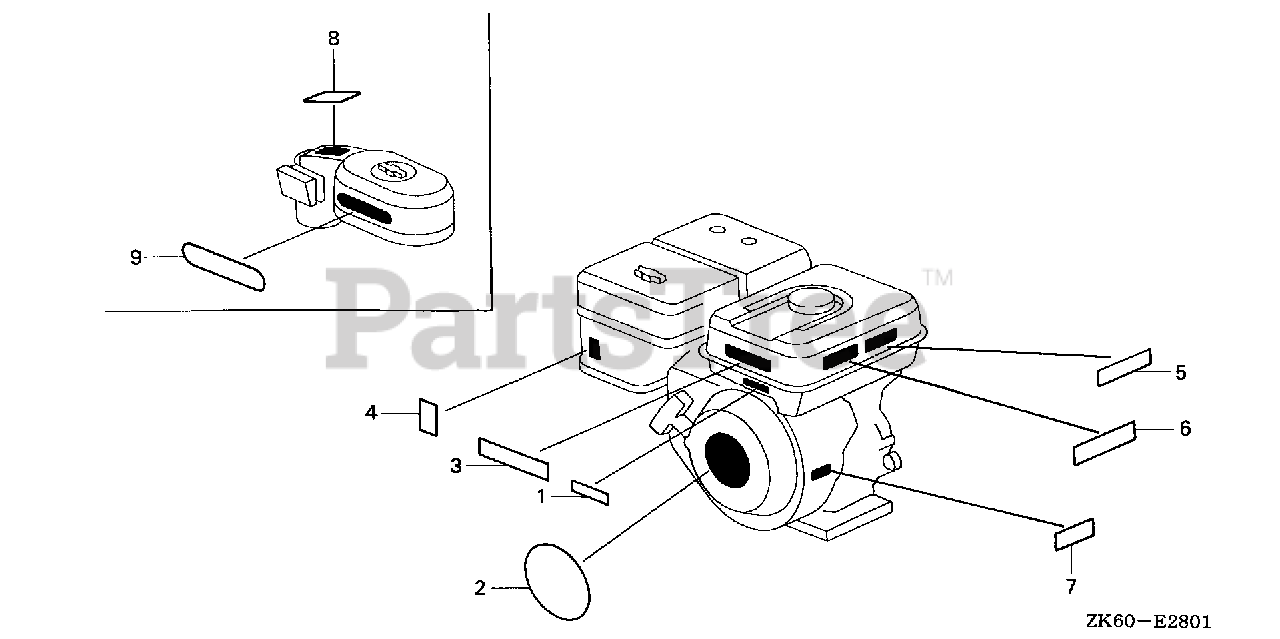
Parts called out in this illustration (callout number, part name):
2	EMBLEM (13. (HONDA)
3	LABEL, CAUTION (ENGLISH, ETC.)
4	MARK, CHOKE (ORANGE)
